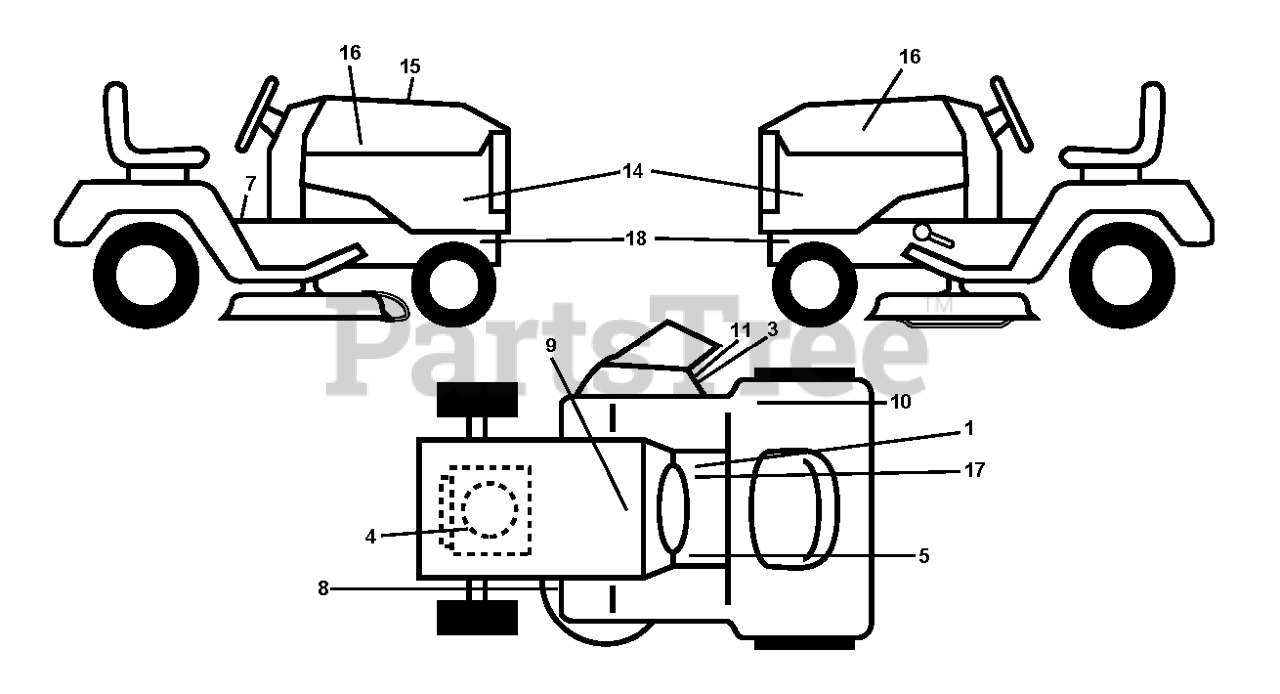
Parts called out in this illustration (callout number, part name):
1	DECAL
3	DECAL, DEFLECT WARNING
4	DECAL
5	DECAL
7	LABEL
8	DECAL.MOWER.SCH.48/54
9	DECAL BTRY SYMBOLS
10	DECAL.FENDER
11	DECAL.INTERNATIONL.CUTFINGER
16	RP.DECAL.BADGE.170MM.TEXTLOGO
17	DECAL PARK BRAKE
